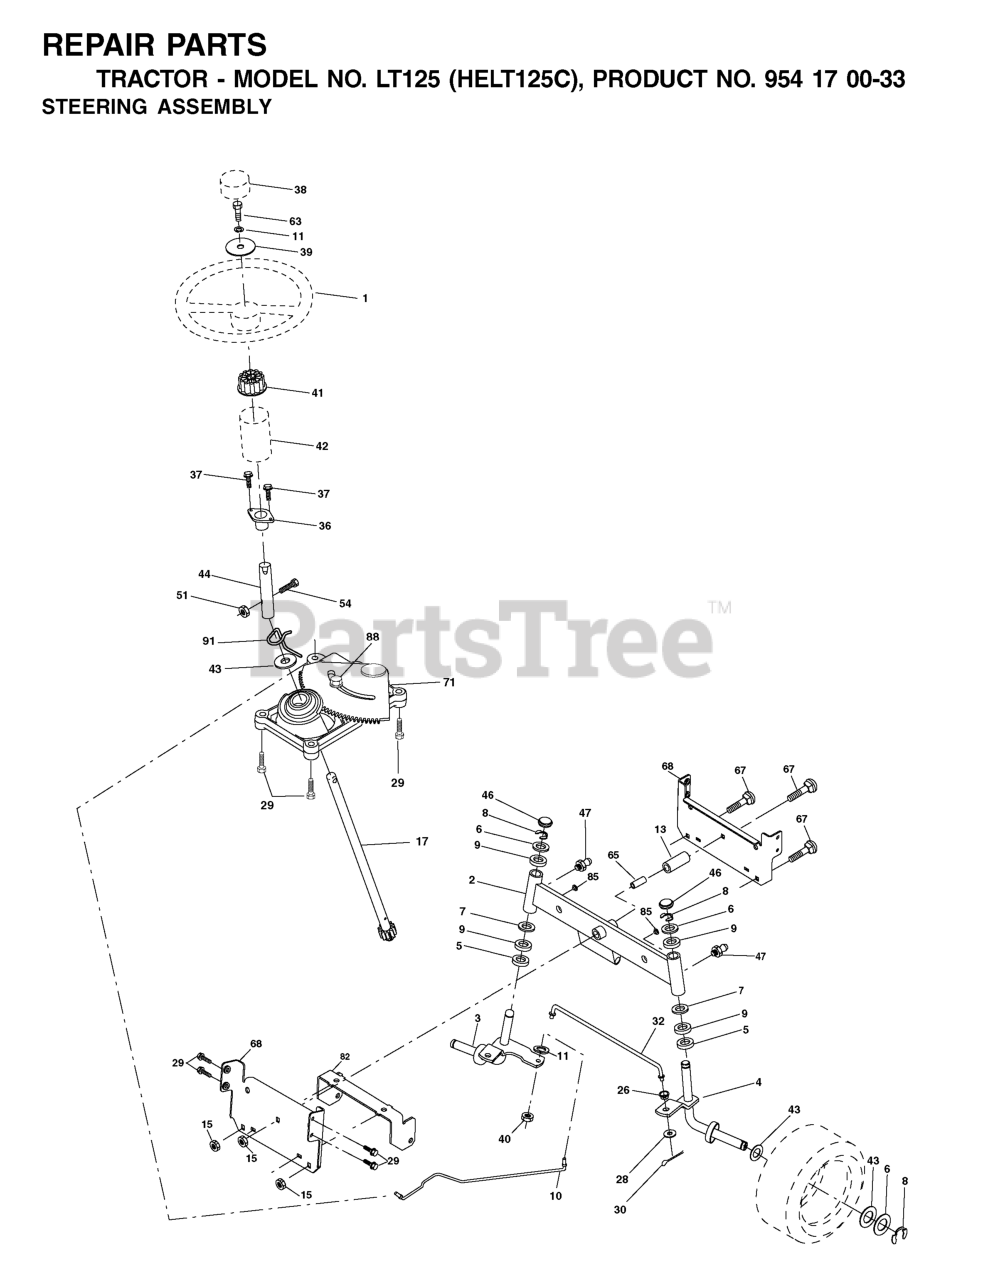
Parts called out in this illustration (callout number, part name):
1	STEERING WHEEL
2	AXLE ASM.
3	SPINDLE.ASM.LH.15"TIRES
4	SPINDLE.ASM.RH.15"TIRES
5	THRUST WASHER
9	BRNG T
10	DRAGLINK.15".TIRES.2001
11	WASHER, LOCK 3/8
13	TUBE, PIVOT AXLE
15	NUT
17	SHAFT ASM
26	BUSHING.DRAGLINK (2 2)
28	WASHER
29	SCREW 3/8-16X3/4
30	COTTER PIN
32	TIE ROD
36	BUSHING, STEERING
37	SCREW.TT.#10-32X.5.3/8.FLANGE
38	INSERT,STR WHEEL
39	WASHER 13/32 X 2-3/8 X 12GA
40	GRIPCO NUT
41	ADAPTER LT
42	BOOT STEERING
44	EXT SHAFT STEERING
46	CAP.SPINDLE.BLACK
47	ZERK M
51	NUT.71038.31-18.HEX.NYLOCK
54	BOLT.5/16-18X1-1/4 FULL.THREAD
65	SPACER BRACE AXLE
67	BOLT CARRIAGE
68	BRACE.AXLE.15"TIRES
71	STEERING ASM
82	BRACKET
85	FASTENER.XMAS.TREE
88	BOLT, SHOULDER 7/16-20
91	CLIP.STEERING
